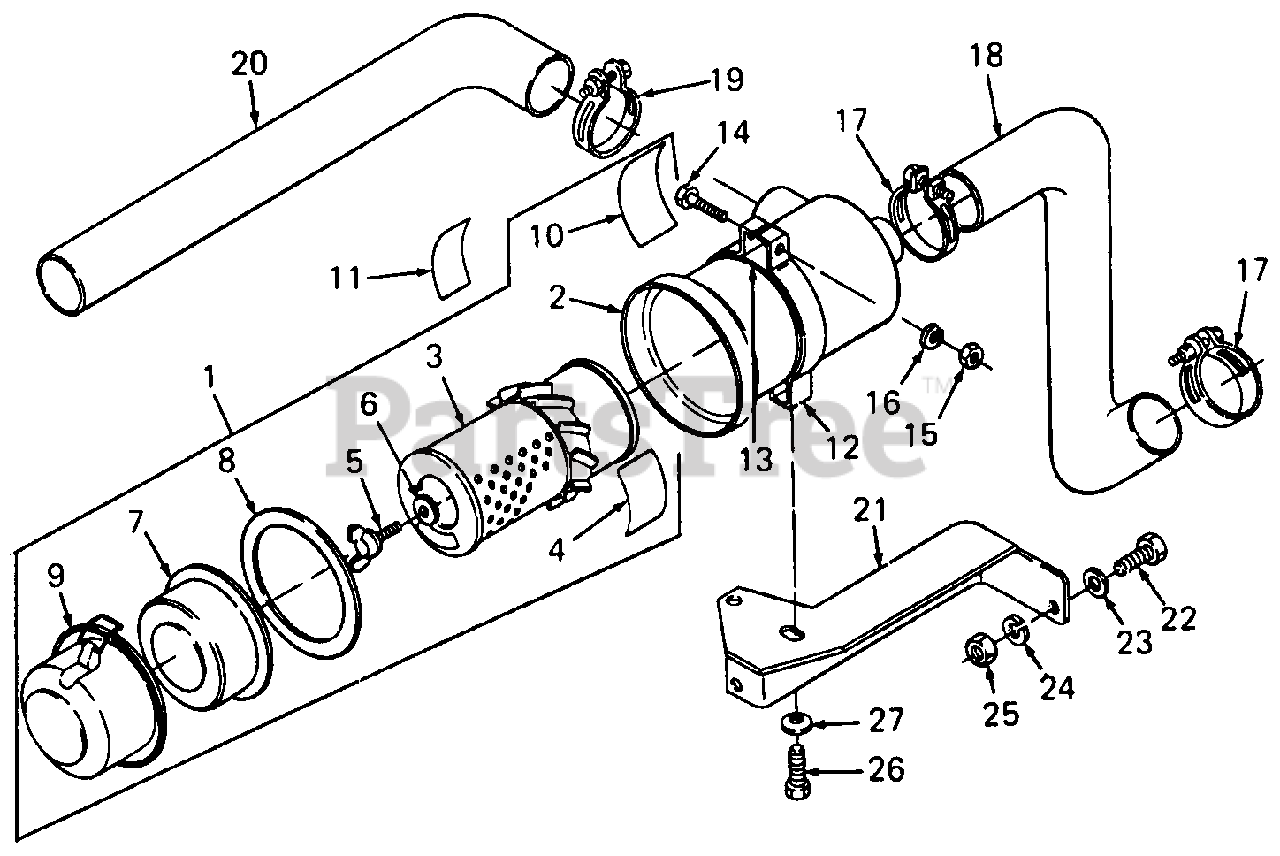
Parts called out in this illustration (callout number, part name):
1	Air Cleaner Assy
2	Body, Air Cleaner
3	Element, Air Cleaner
4	Label, Air Cleaner Element
6	Washer w/Rubber
7	Cover, Baffle
8	Gasket, Air Cleaner Cover
9	Cover, Air Cleaner
10	Label, Air Cleaner
11	Label, Ether Caution
12	Band, Air Cleaner
16	Washer, Spring
17	Clamp, Hose
18	Hose, Diesel Air Inlet
19	Clamp, Hose
20	Hose, Air Intake
21	Bracket, Air Cleaner Mtg
22	Screw, Hex Cap, 5/16-18 X .75 Lg GR5
23	Washer, Flat, .344 X 1.5 X .105 Thk
24	Washer, Lock, 5/16
25	Nut, Hex, 5/16-18 GR5
26	Screw, Hex Cap, M8-1.25 X 20 mm GR5
27	Washer, Bell, .345 X .88 X .060 Thk
